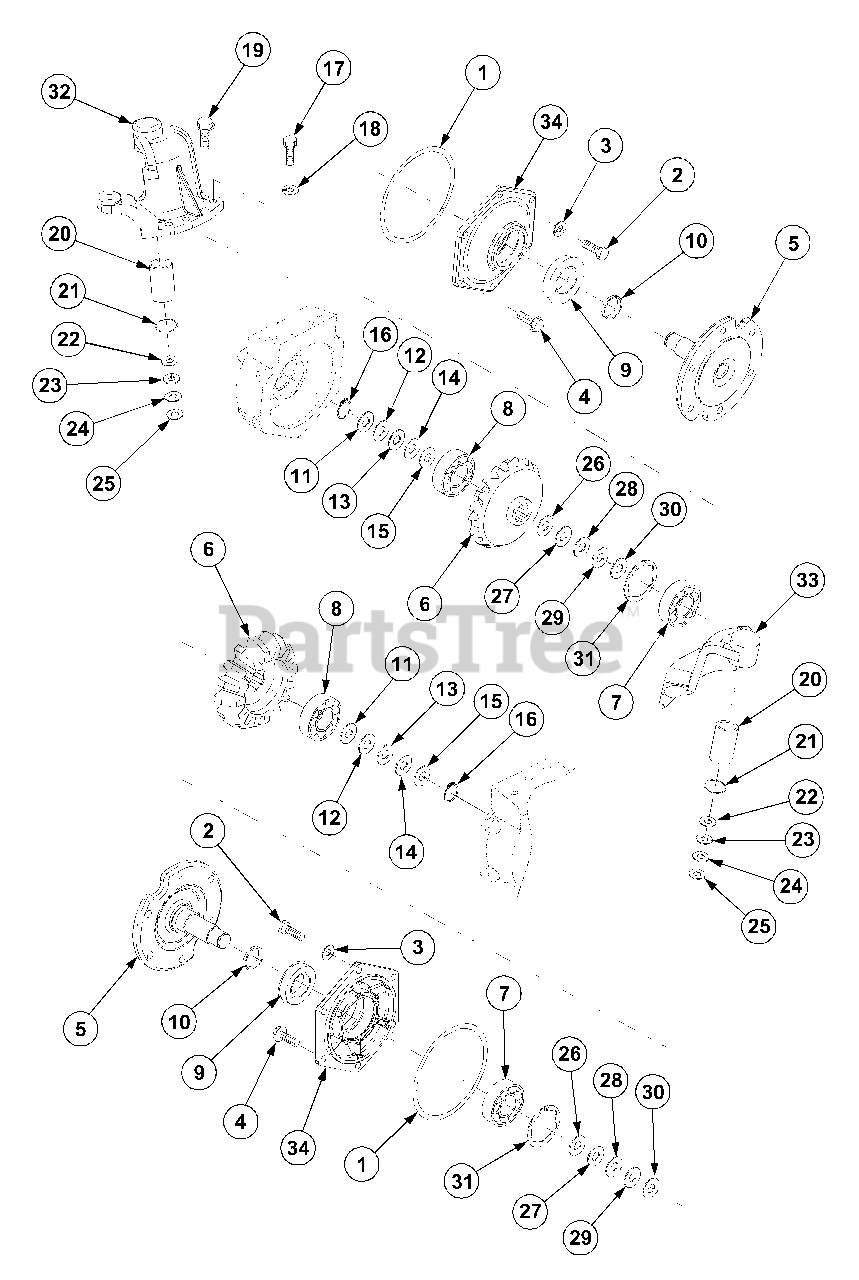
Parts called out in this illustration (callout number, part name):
3	Washer,Spring
4	Bolt,w/Washer
5	Shaft
16	C-ring
18	Washer,Spring
19	Bolt,w/Washer
22	Liner F,Thrust
23	Liner G,Thrust
24	Liner H,Thrust
25	Liner J,Thrust
32	Knuckle Arm L.H
33	Knuckle Arm R.H
